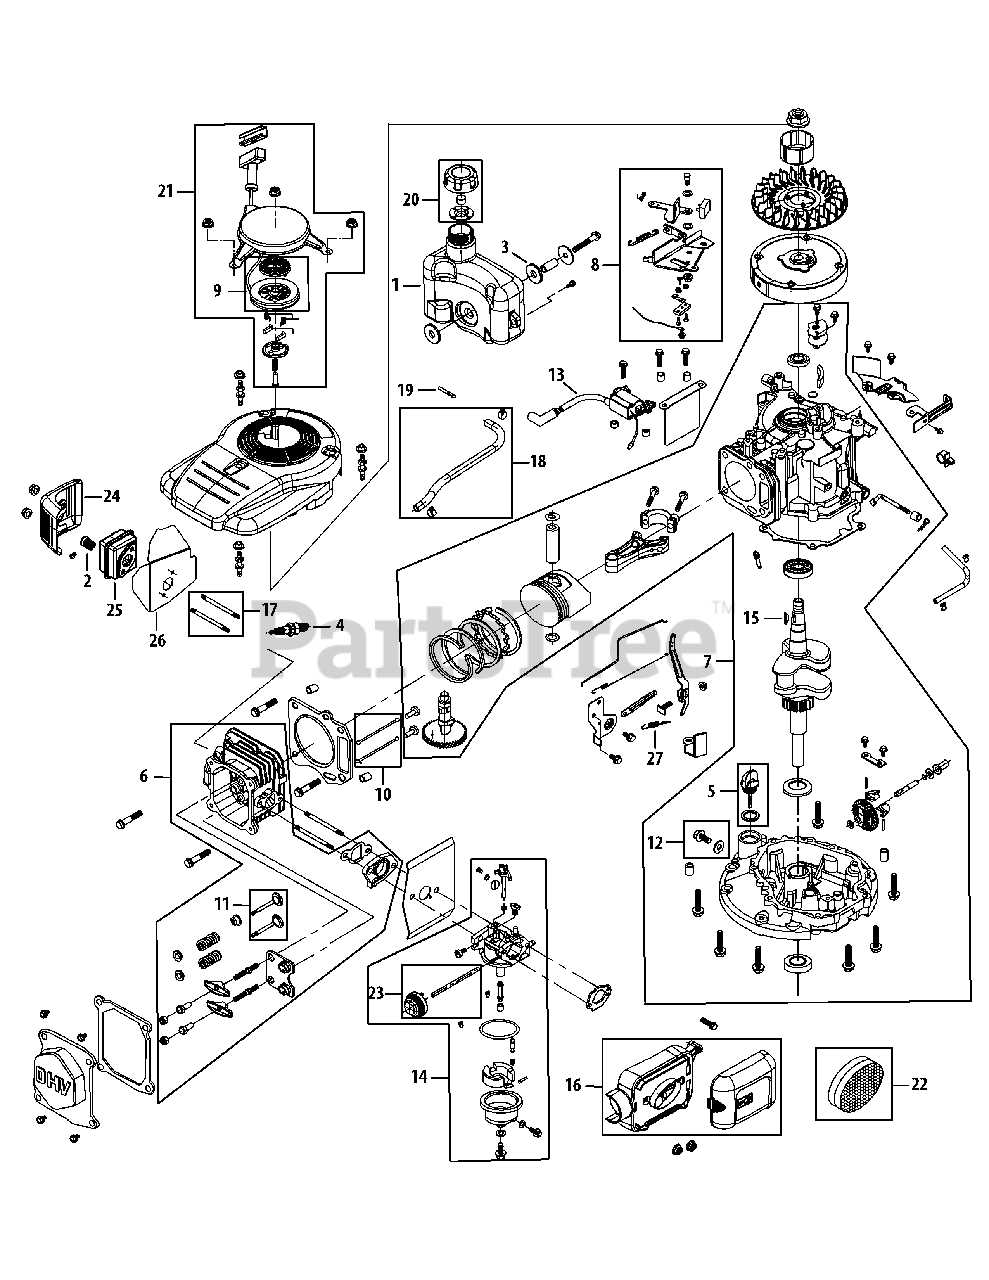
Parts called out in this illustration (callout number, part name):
1	Fuel Tank
2	Spark Arrestor
3	Rubber Fuel Tank Mounting Washer
4	Spark Plug
5	Dipstick Assembly
6	Cylinder Head Assembly
7	Short Block Assembly
8	Stop Switch and Brake Assembly
9	Recoil Spring and Pulley Assembly
10	Push Rod Kit
11	Valve Kit
12	Oil Drain Plug and Washer Assembly
13	Ignition Coil
14	Carburetor Assembly
15	Flywheel Key
16	Air Cleaner Housing Assembly Complete
17	Muffler Stud Assembly
18	Fuel Line Kit - Inc. hose & clamps
19	Fuel Filter
20	Fuel Cap Assembly
21	Recoil Starter Assembly
22	Air Filter
23	Primer Assembly
24	Muffler Shield
25	Muffler Assembly
26	Muffler Gasket /Heat Shield
27	Governor Return Spring
